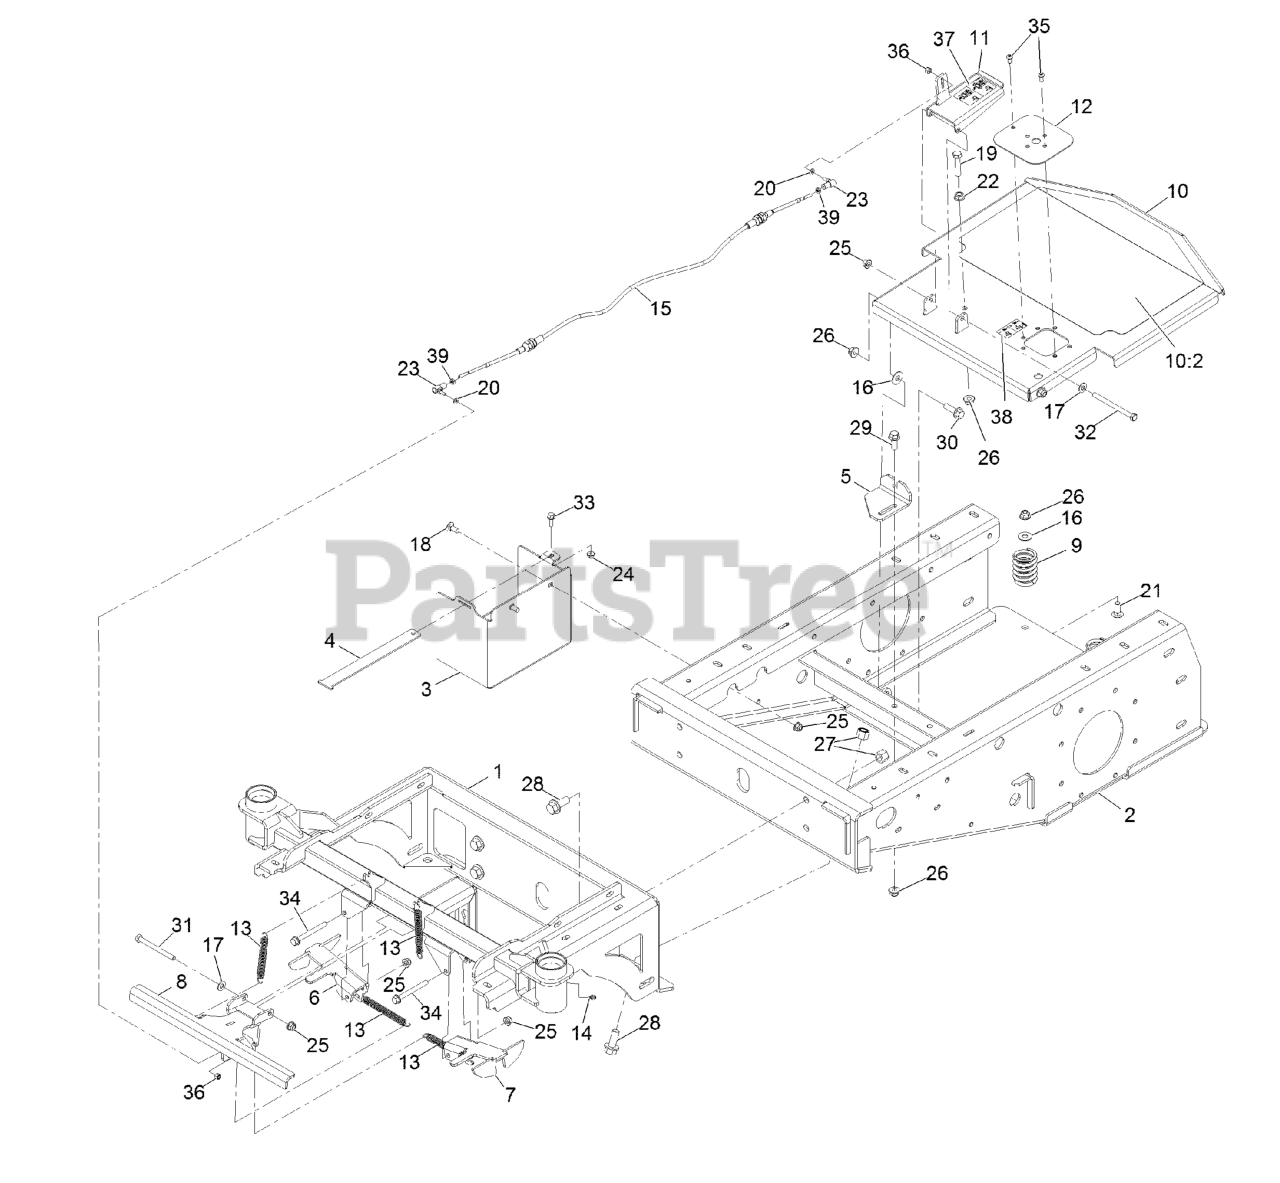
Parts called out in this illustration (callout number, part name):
1	Frame-Front
2	FRAME-REAR
3	Box-Battery
4	STRAP-BATTERY
5	Bracket, Lower Cable
6	Wing-Capture, Rt
7	Wing-Capture, Lt
8	Capture-Lcs
9	SPRING-COMPRESSION
10	Plate-Foot
10:2	PAD-GRIP
11	Pedal-Foot
12	Panel, Foot Switch
13	SPRING-EXTENSION
14	FITTING-GREASE, ZERK
15	CABLE-CASTER, LOCKING
16	WASHER-FLAT
18	SCREW-CARR
19	Screw-HH
20	WASHER-FLAT
21	SCREW-CARR
22	Nut-Hex Flange
23	BALL JOINT-SS
24	Nut-Hex Flange
25	Nut-Hex Flange
26	Nut-Hex Flange
27	Nut,1/2-13,NYL INS,ST/ST,18-8
28	SCREW-HHF
29	SCREW-HHF
30	SCREW-HHF
31	SCREW-HH
32	Screw-HH
33	Screw-HHF
34	SCREW-HHF
35	Screw-HSBH
36	Nut,NYL Lock,#10-32,ST/ST 18-8
37	Decal-Lock, Caster
38	Decal-Spray Foot Button
39	Nut,Hex Jam Mch Scr,10-32,Sst
